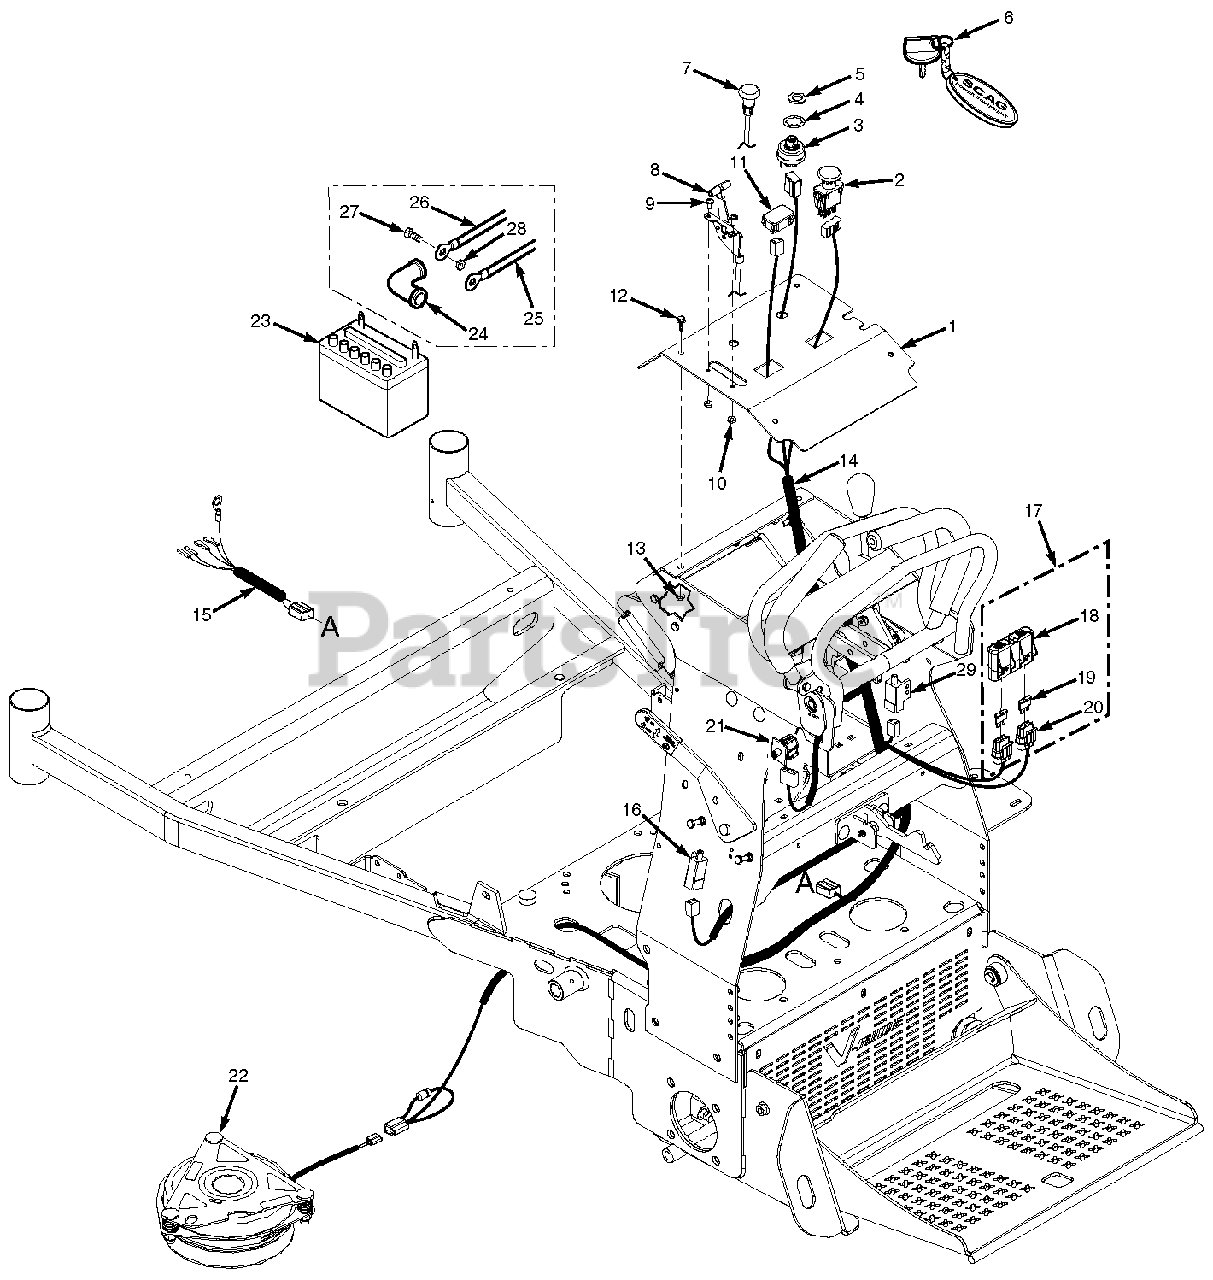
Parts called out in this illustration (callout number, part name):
1	Instrument Panel w/Decal
2	Switch, PTO - 10 Amp
3	Key Switch
4	Lockwasher, 5/8" Internal Tooth
5	Nut, 5/8-32 Special
6	Key Chain w/ Keys
6	Key w/Shroud
7	Choke Control, SVR
8	Throttle Control, SVR
9	Bolt, Carriage #10-24 x 1/2"
10	Locknut, #10-24
11	Hourmeter
12	Bolt, Hex Head 1/4-20 x .63
13	Nut, Serrated Flange 1/4-20
14	Wire Harness, SVR
15	Wire Harness Adapter, Kawasaki
16	Switch, Interlock
17	Double Fuse Assy.
18	Cover, Sealed Double
19	Fuse, 20 Amp
20	Fuse Holder
21	Switch, Double Pole - Plunger
22	Clutch w/Tag (36A, 48V, 52V)
22	Clutch w/Tag (61V)
23	Battery (not avail. through Scag)
24	Rubber Boot
25	Cable, Battery Black 18"
26	Cable, Battery Red 18"
27	Bolt, Hex Head 1/4-20 x 3/4"
28	Nut, 1/4-20
29	Switch, Interlock
